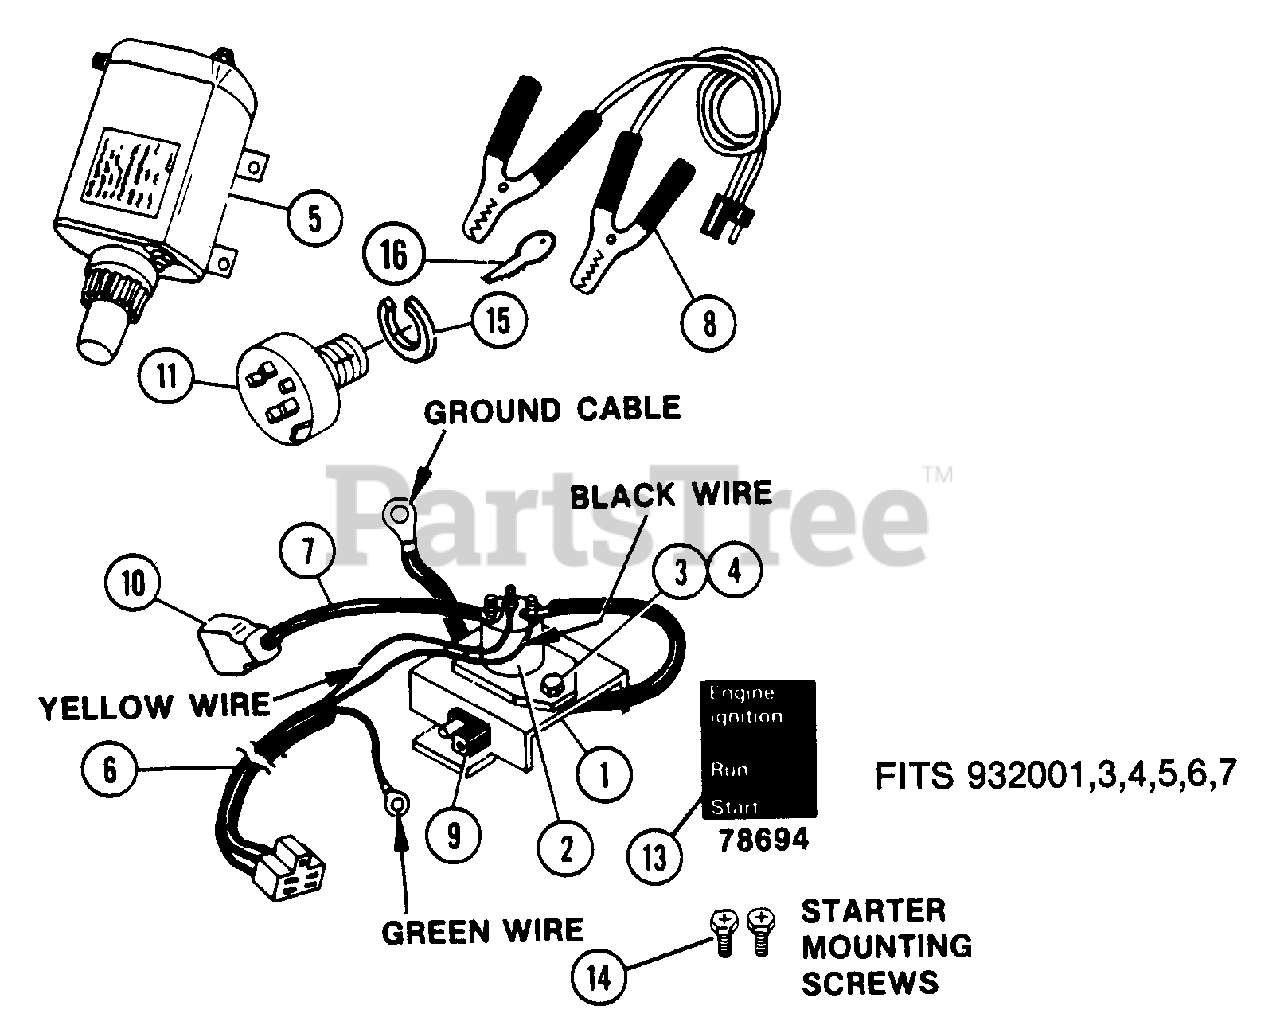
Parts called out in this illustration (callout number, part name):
1	BRACKET
2	SOLENOID
3	BLT-HEX .25-20X.50 PL GR2
4	NUT-LK-CTR .250-20 PL
6	WIRING HARNESS
8	JUMPER CABLE W/CONNECTOR
9	ADAPTER LEAD W/CONNECTOR
10	INSULATOR
11	SWITCH ASSEMBLY
13	DECAL-SWITCH
14	SCR-TAP .250-20X.62 CRHWH PL
15	WSHR-LK-INT .625X.045 PL
16	KEYS
